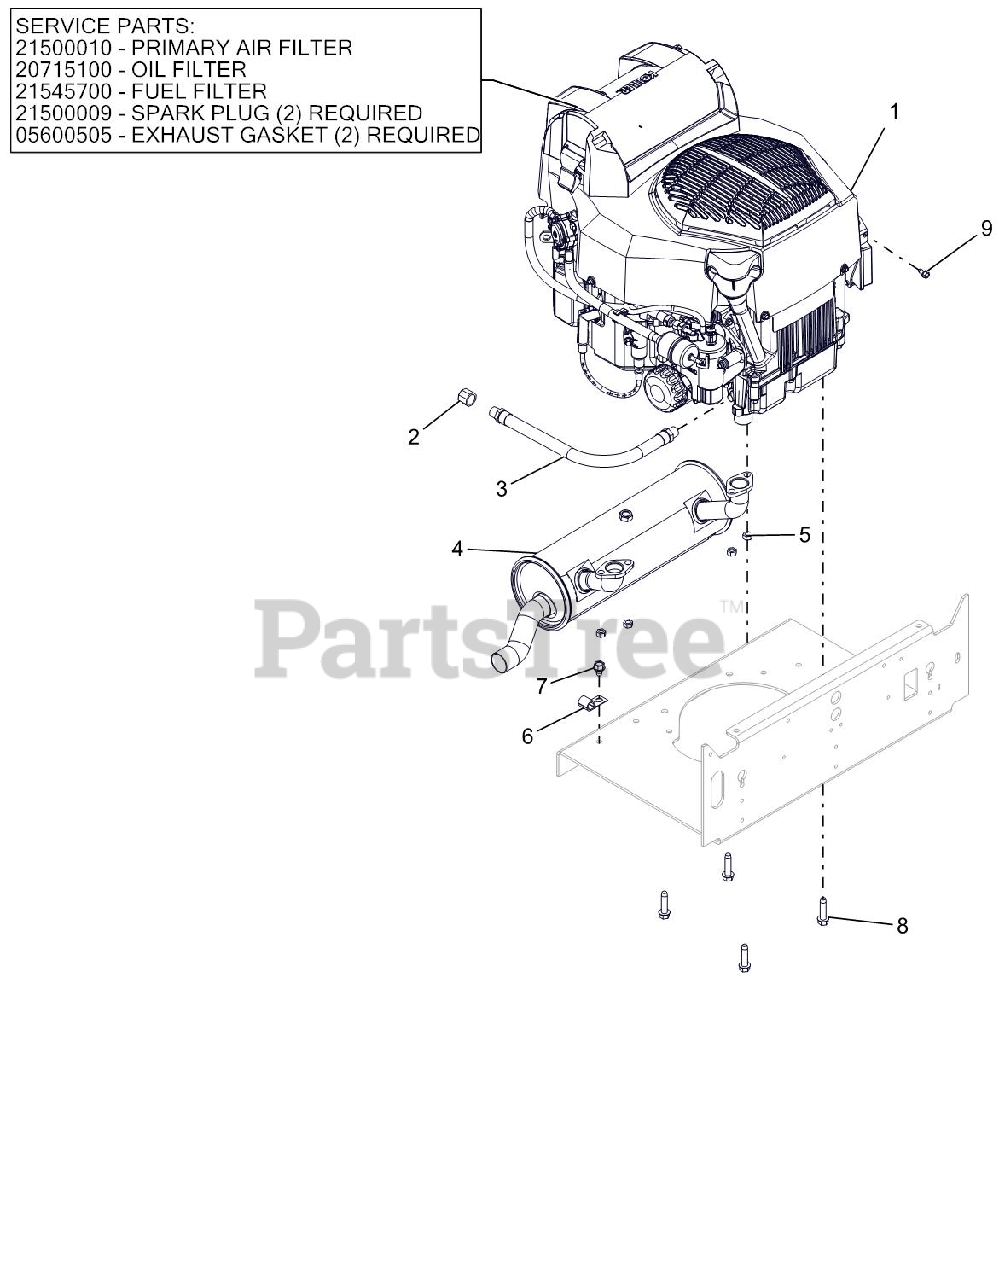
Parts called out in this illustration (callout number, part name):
1	ENGINE, KOHLER EZT725 EFI
1	PRIMARY AIR FILTER
1	OIL FILTER
1	FUEL FILTER
1	SPARK PLUG
1	EXHAUST GASKET
2	PIPE, CAP 3/8 NPT FEMALE
3	HOSE, HYD .38-11-OK M6N0-M6N0
4	MUFFLER,
5	NUT-LK-TOP M8-1.25 YWZC
7	SCR-TAP .38-16X.50 HWH TR YWZ
8	SCR-TAP .38-16X1.50 HWH TR YZ
9	SCR-TAP .25-20X.50 HWH TR YWZ
